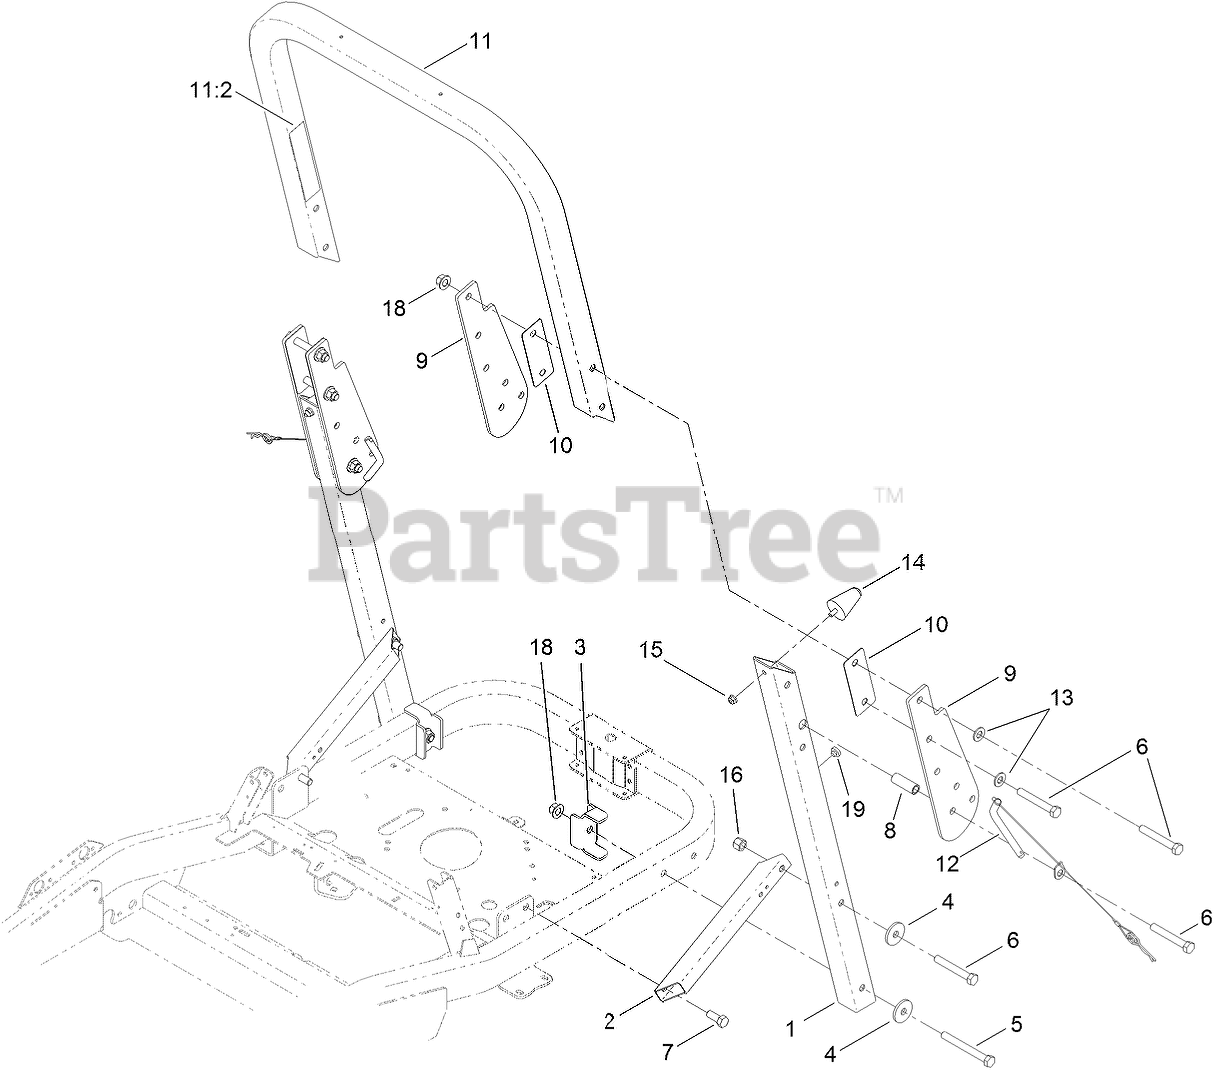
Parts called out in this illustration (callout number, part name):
1	TUBE-ROPS, LOWER
2	TUBE-SUPPORT, ROPS
3	BRACKET-REINFORCING
4	WASHER-THRUST
5	SCREW-HH
6	SCREW-HH
7	SCREW-HH
8	SPACER
9	BRACKET-PIVOT, ROPS
10	SPACER-ROPS
11	UPPER ROPS ASM
11:2	DECAL-WARNING
12	PIN-ROPS
13	WASHER-FLAT
14	BUMPER-RUBBER
15	NUT-HF, NI
16	NUT-HEX
18	NUT-LOCK
19	BUMPER
